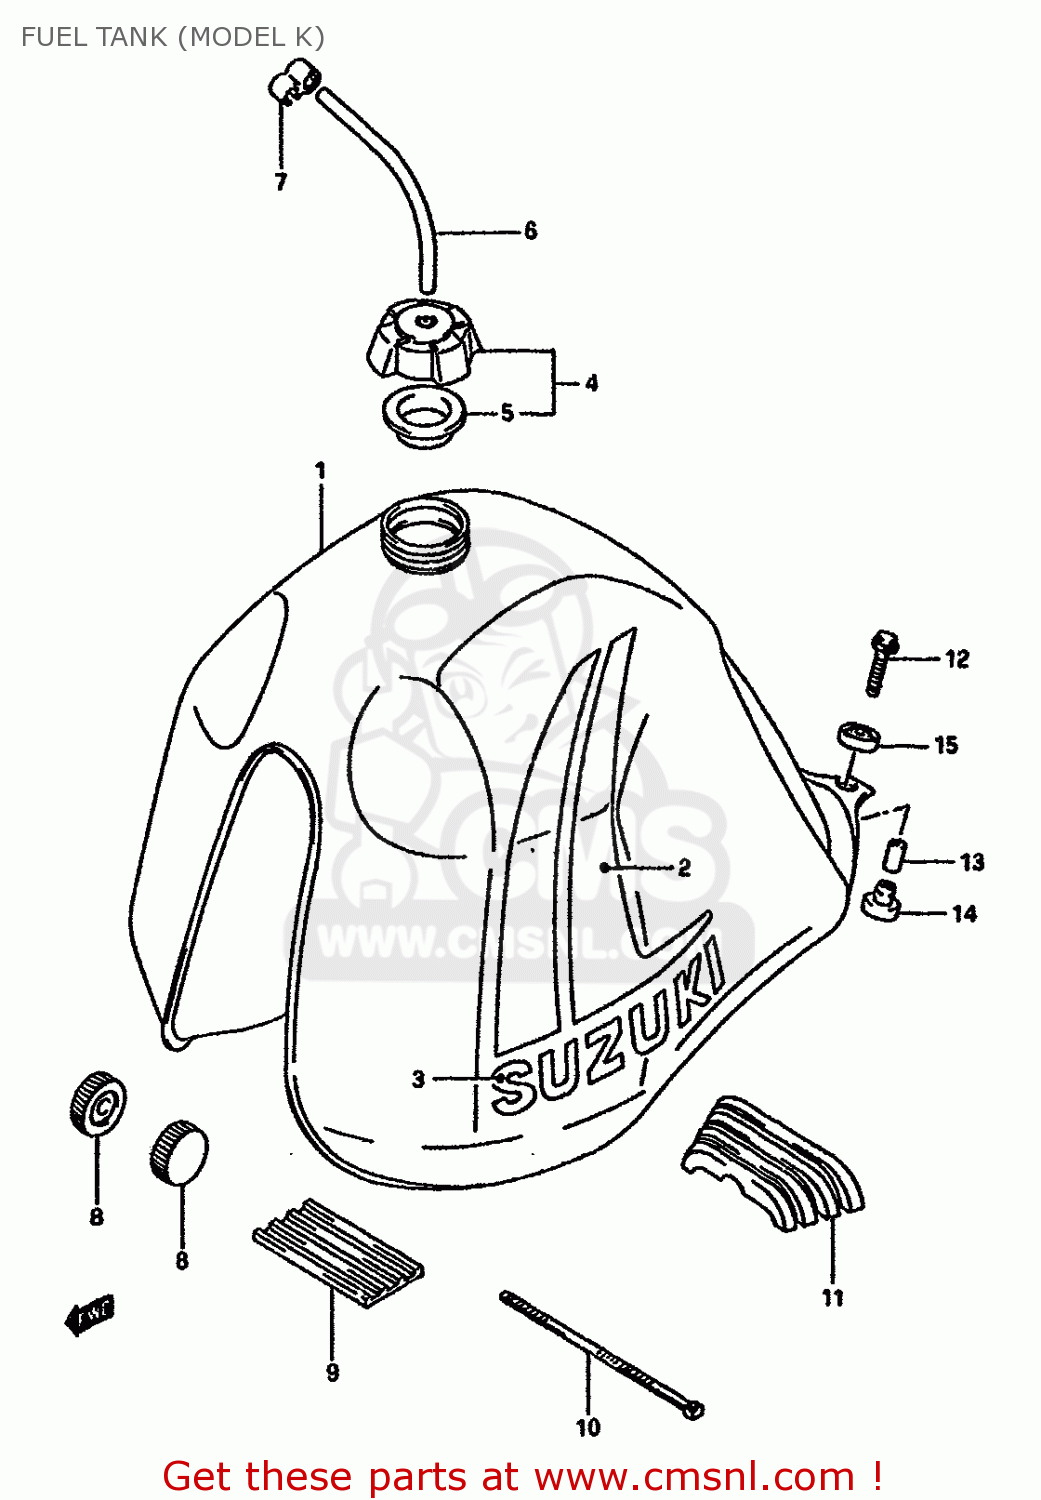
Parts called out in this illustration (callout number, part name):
1	TANK ASSY,FUEL (BLUE)
2	TAPE SET,FUEL TANK
3	EMBLEM,FUEL TANK(BLACK)
4	CAP SET,FUEL TANK
5	GASKET,FUEL TANK CAP (NAS)
6	HOSE
7	CLAMP,FUEL TANK BREATHER HOSE
8	CUSHION
9	CUSHION,FUEL TANK UPR FR
10	CLAMP
11	CUSHION,FUEL TANK RR
12	BOLT
13	SPACER
14	BOLT
15	SPACER
16	CUSHION
17	CUSHION
18	LABEL,FUEL CAUTION
